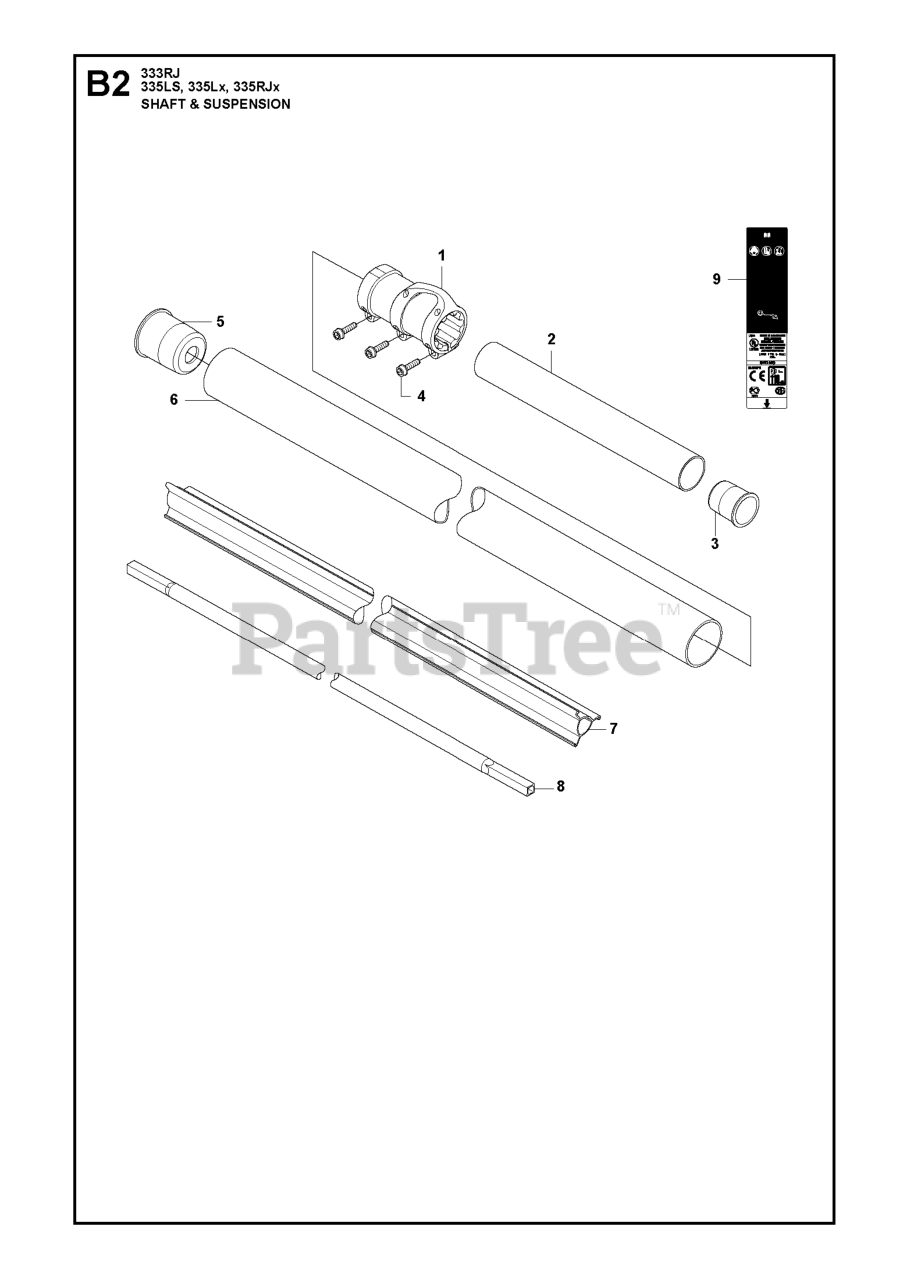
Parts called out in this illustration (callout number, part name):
1	SLEEVE
2	TUBE
3	SPACER SLEEVE
6	TUBE
7	GUIDE
8	SHAFT
9	RP WARNING DECAL
